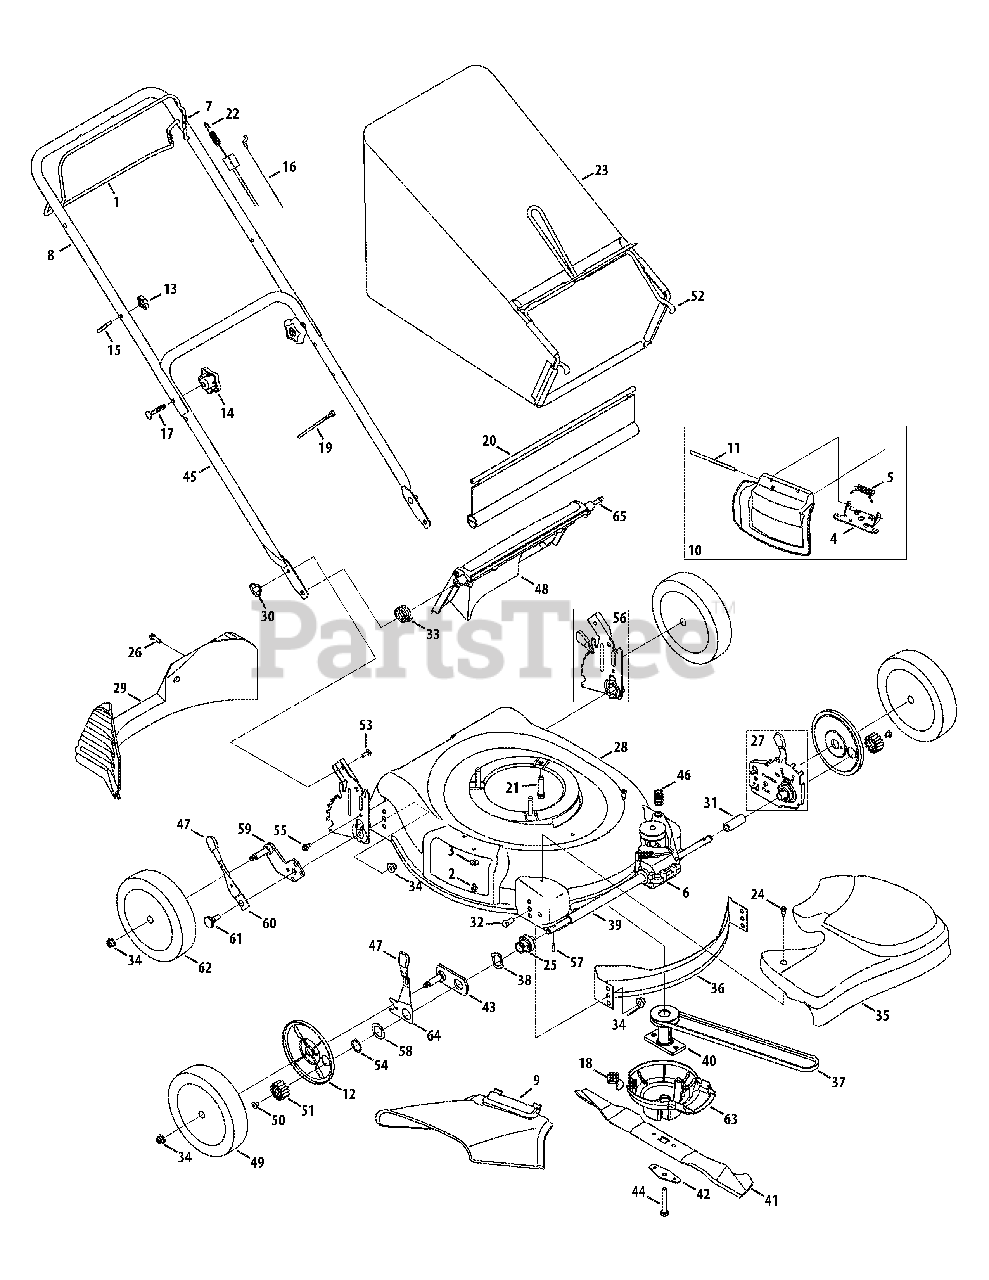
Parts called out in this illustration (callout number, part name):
1	Drive Control
2	TT Screw 1/4-20 x 0.5
3	Bell Washer.265 x 0.75
4	Deflector Chute Adapter
5	Torsion Spring
6	Transmission Assembly
7	Blade Control
8	Upper Handle
9	Chute Deflector
10	Mulch Plug Complete
11	Hinge Pin
12	Wheel Dust Cap
13	Handle Knob
14	Star Knob
15	Eye Bolt
16	Control Cable - 40.75"
17	Carriage Bolt 5/16-18 x 2.0
18	Engine Baffle Bracket
19	Cable Tie
19	Guide, Cable
20	Rear Trailing Shield
21	Self-Tapping Sems Screw
22	Drive Cable - 51"
23	Grass Bag
24	Shoulder Screw # 12 -24
25	Front Bearing Assembly
26	Screw, 1/4-15 x 1.000
27	Height Adjustment Ass’y - RH
27	Height Adjustment Ass’y - LH
28	21" Deck - Red
28	21" Deck - Black Jack
29	Rear Baffle
30	Wing Nut
31	Slev. Spacer 1.4" Lg.
32	Hex Screw, 3/8-16 x.75
33	Torsion Spring - RH
34	Flange Lock Nut, 3/8-16
35	Transmission Cover
36	Front Baffle
37	V-Belt
38	Wave Washer
39	Sleeve Spacer 8.985" Lg.
40	Blade Adapter, 25mm
41	21" Mulching Blade
42	Blade Bell Support
43	Pivot Plate Assembly
44	Hex Screw 3/8-24 x 2.50
45	Lower Handle
46	Belt Tension Spring
47	Adjustment Knob
48	Rear Discharge Door
49	Front Wheel
50	Screw, 1/4-20 x .390
51	Gear 14T RH FWD
51	Gear 14T LH FWD
52	Grass Bag Frame
53	Carriage Bolt 1/4-20
54	Snap Ring
55	TT Scr. w/Washer 1/4-20 x.625
56	Handle Bracket Assembly - RH
56	Handle Bracket Assembly - LH
57	Dowel Pin
58	Washer
59	Pivot Arm Assembly - RH
59	Pivot Arm Assembly - LH
60	Rear Spring Lever
61	Shoulder Scr.500 Dia. x.434
62	Rear Wheel
63	Engine Baffle
64	Front Lever - RH
64	Front Lever - LH
65	Pivot Rod
